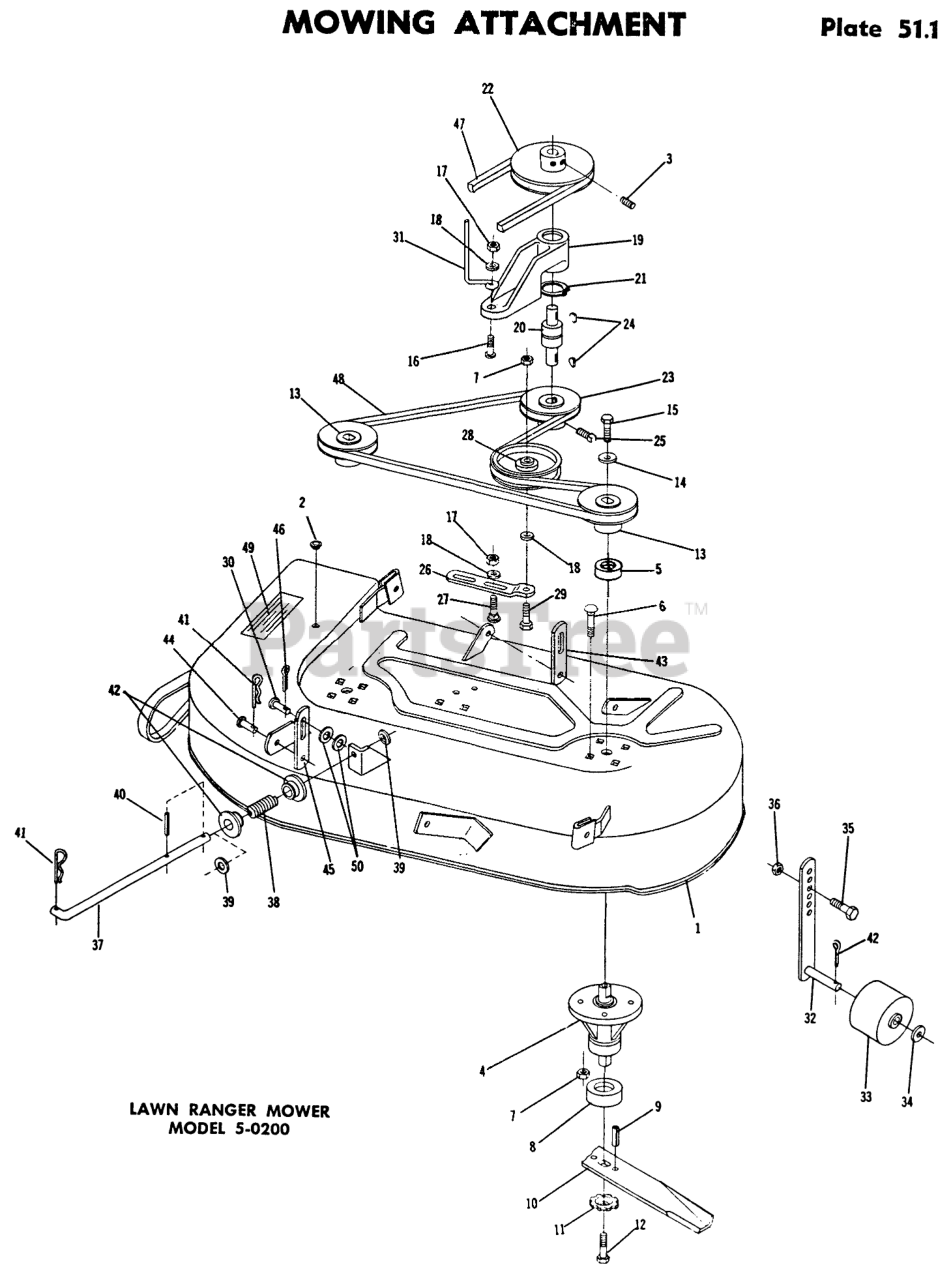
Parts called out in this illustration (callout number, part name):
2	Plug Button
3	Set Screw
6	Bolt Carriage 3/8-16 x 1
9	SPIROL ROLL PIN
12	Bolt 3/8-16 x 7/8
13	PULLEY
14	WASHER
15	Bolt 3/8-16 x 3/4 Nylok
16	Bolt 3/8-16 x 1
17	3/8-16 E.S.
18	Washer
20	Bearing-Integral Shaft 5/8
24	KEY-WOODRUFF
25	Set Screw-5/16-18 x 3/8
27	Bolt 3/8-16 x 1
29	Bolt Hex 3/8-16
33	ROLLER ASSY
34	Washer
35	Bolt 5/16-18 x 1
36	Nut 5/16-18
39	Washer
40	PIN-ROLL
41	Hairpin
42	BUSHING
43	LIFT LINK
44	Clevis Pin 3/8 x 3/4
46	Hairpin
50	Washer
